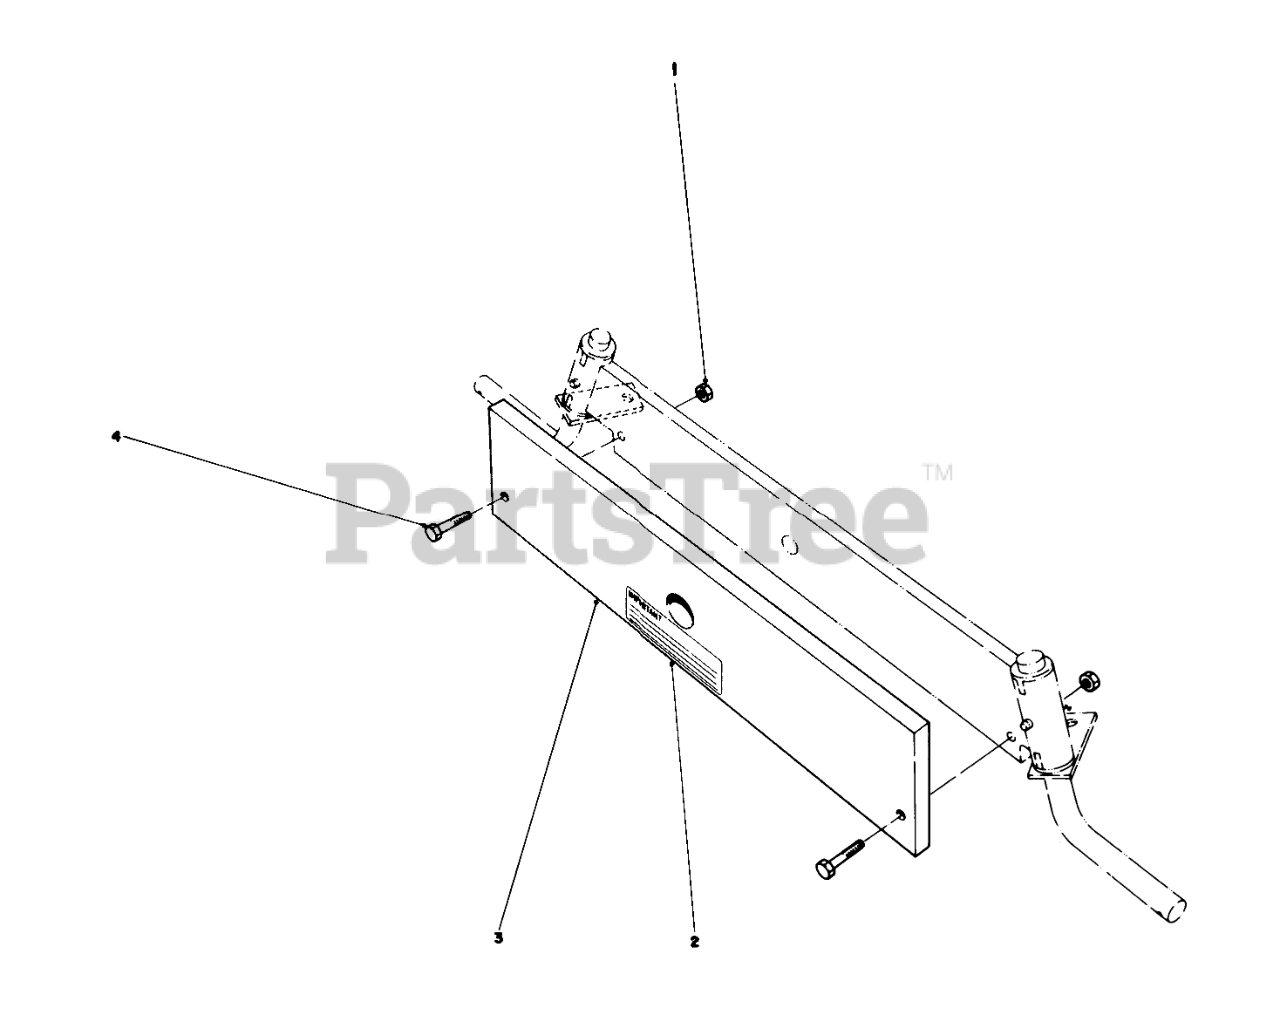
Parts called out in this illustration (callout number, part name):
1	NUT-LOCK, CONE
2	Decal-Warning
3	COUNTERWEIGHT B
4	SCREW-HH
